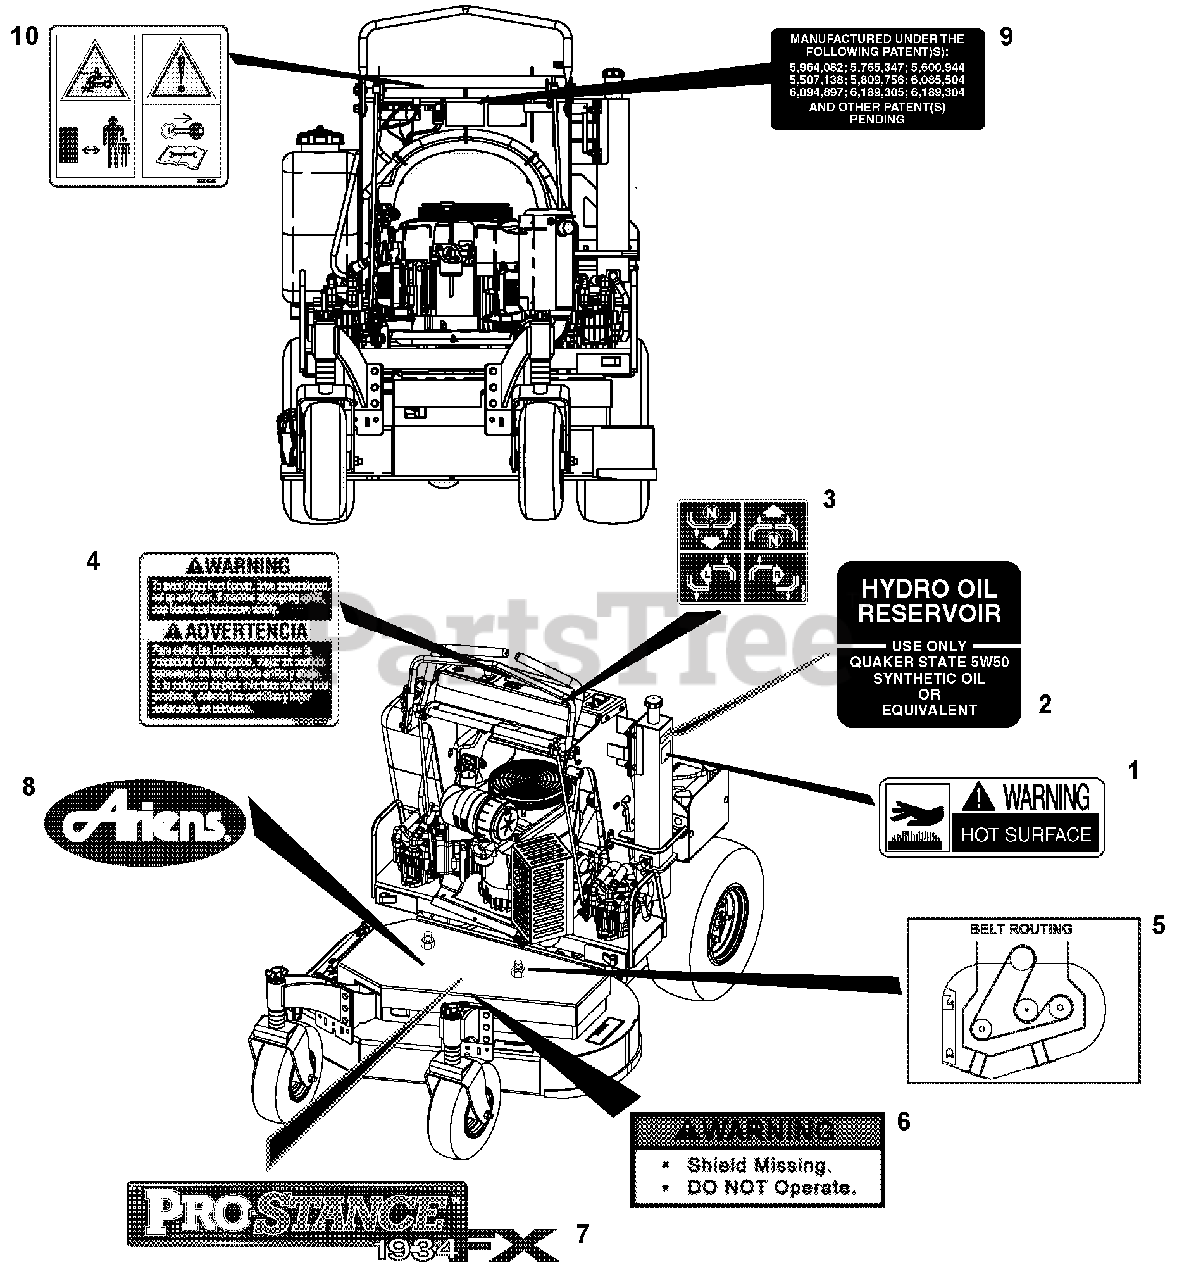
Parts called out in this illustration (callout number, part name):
1	DECAL, WARNING-HOT SURFACE (RE
2	DECAL, HYDRO OIL RESERVOIR
3	DECAL, INSTRUCTIONAL-STEERING
4	DECAL, WARNING-AVOID TIPOVER
5	DECAL, BELT ROUTING 34
6	DECAL, WARNING-SHIELD
7	DECAL, PROSTANCE 1934 FX
8	DECAL, ARIENS
9	DECAL, PATENT
10	DECAL, ARIENS
